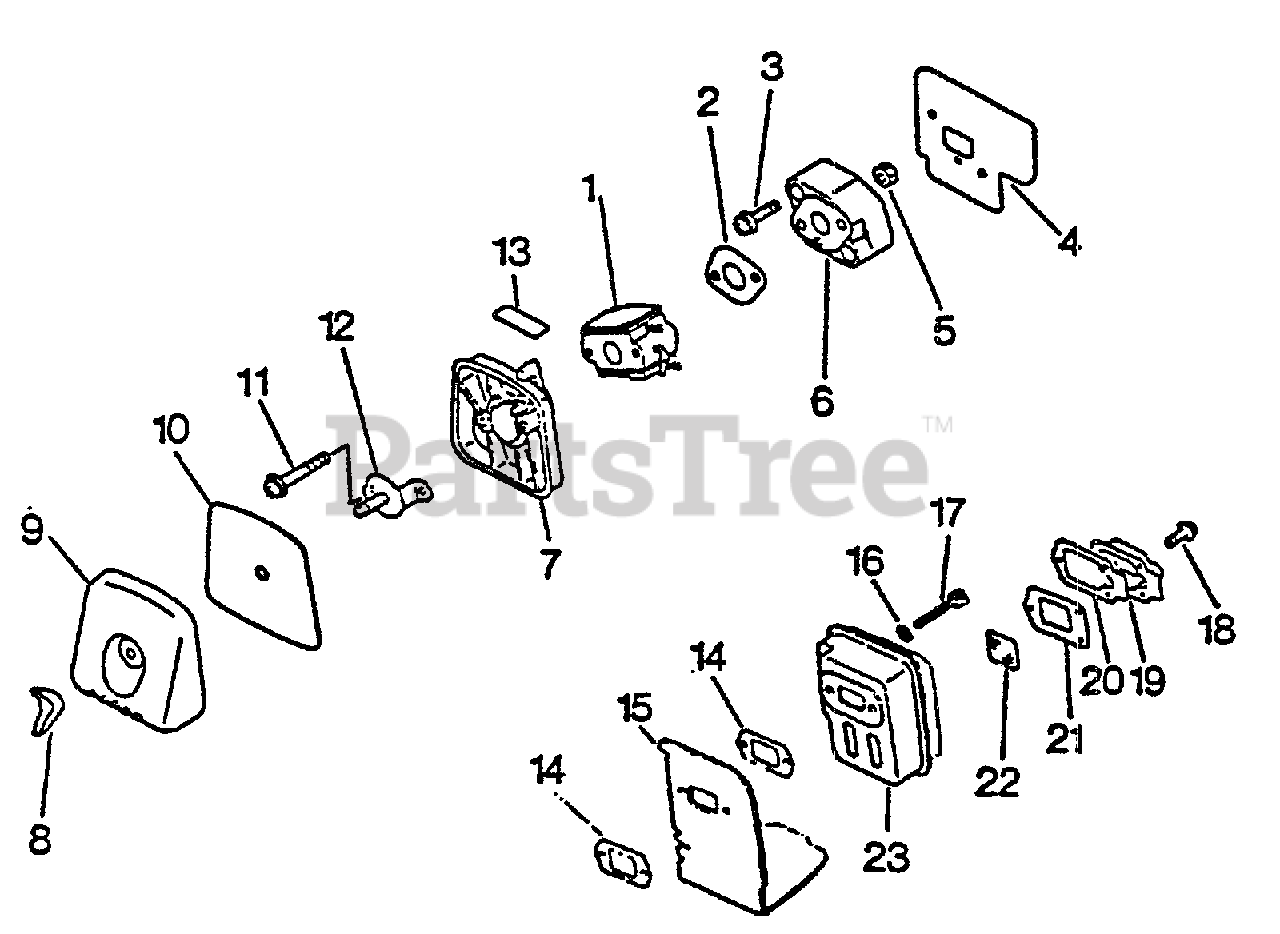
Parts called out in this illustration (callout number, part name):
1	CARBURETOR C1U-K14
2	GASKET, INTAKE
3	SCREW - 5X22
4	GASKET, INTAKE
6	INSULATOR, INTAKE
7	AIR FILTER CASE KIT - BLACK
8	WINGNUT - 6
9	COVER, AIR FILTER - BLACK
10	FILTER, AIR
11	SCREW - 5X64
12	PLATE, PREVENT
13	LABEL - CHOKE
14	GASKET, EXHAUST
15	SHIELD, EXHAUST
16	WASHER - 5
17	SCREW - 5X55
18	SCREW - 4X10
19	GUIDE, EXHAUST - INNER
20	GASKET, EXHAUST - INNER
21	GASKET, EXHAUST
22	SCREEN, SPARK ARRESTOR
